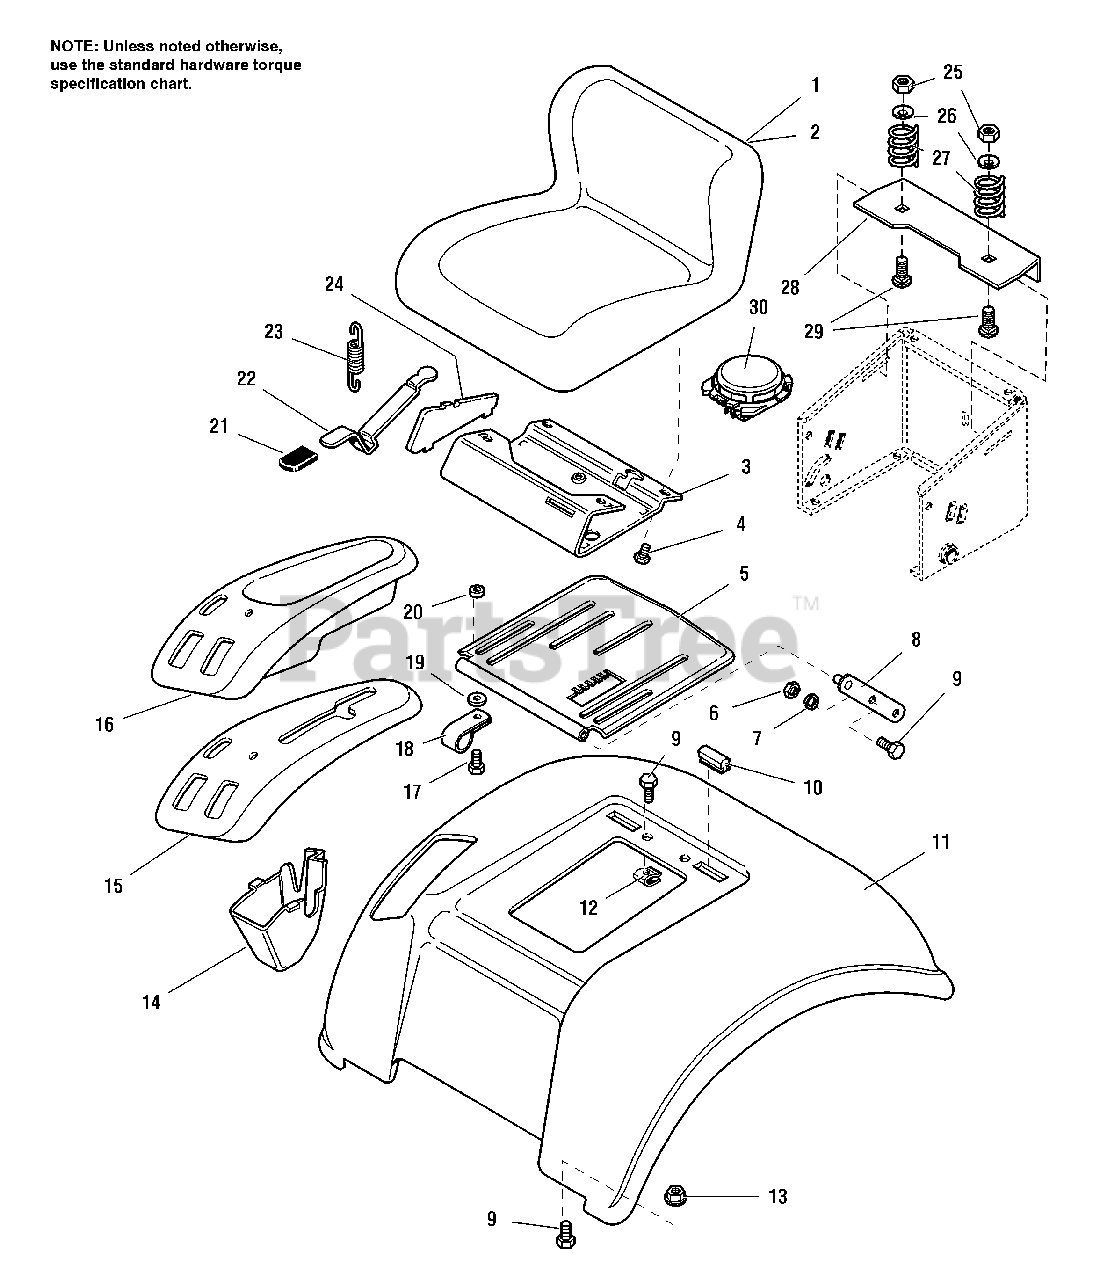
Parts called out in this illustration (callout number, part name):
1	SEAT ASSEMBLY
2	COVER, Seat
3	SLIDE, Seat
4	CAPSCREW, Whiz Lock Hex Hd, 5/16-18 x 1/2
6	NUT, Hex, Full, 5/16-18
7	LOCKWASHER, 5/16
8	BAR ASSEMBLY, Seat Pivot
9	CAPSCREW, Whiz Lock Hex Hd, 5/16-18 x 3/4
10	STOP, Rubber Seat
11	SEAT DECK, Orange
11	SEAT DECK, Red
12	SPEED NUT, Tinnerman Lug Type, 5/16-18
13	NUT, Hex Flange Whiz-Lock, 5/16-18
14	GUARD, Splash, Pod
15	CONTROL POD, Gear
16	CONTROL POD, Hydro
17	CAPSCREW, Taptite Hex Washer Hd, 5/16-18 x 5/8
18	CLAMP, Wire
19	WASHER, 5/16
22	LEVER, Seat Latch
23	SPRING, Extension
24	SIDE PANEL, Seat Slide
25	NUT, Hex Nylon Lock, 5/16-18
27	SPRING, Seat
28	PLATE, Spring Support
29	CARRIAGE BOLT, 5/16-18 x 1
30	SWITCH, Seat
